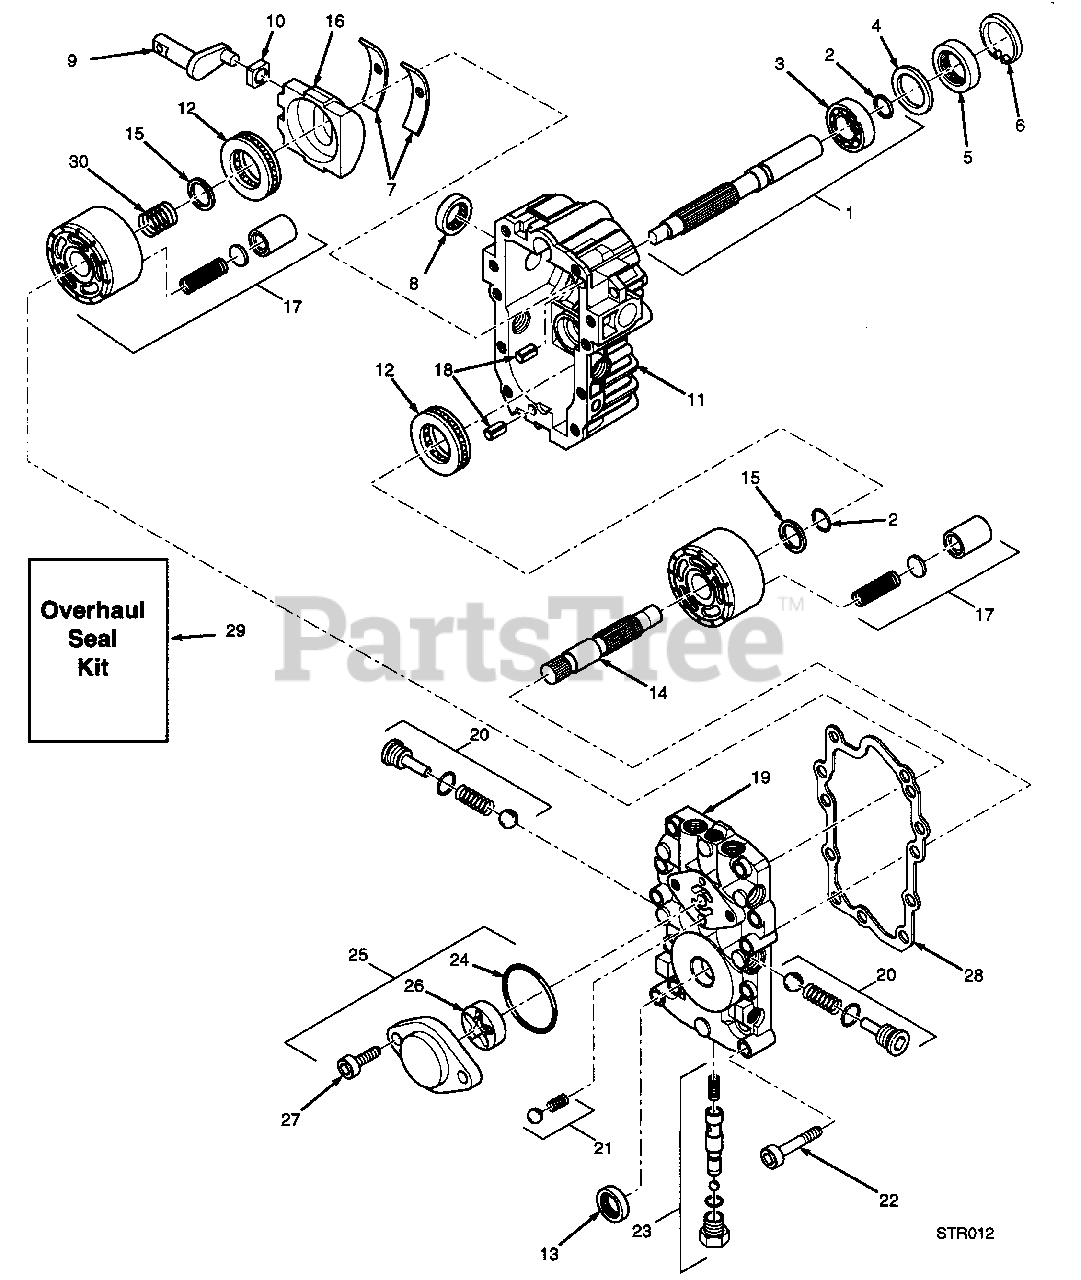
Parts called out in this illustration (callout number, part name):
1	PUMP SHAFT KIT
2	WIRE RETAINING RING
3	BALL BEARING
4	SPACER
6	RETAINING RING
7	CRADLE BEARING
9	TRUNNION ARM
10	SLOT GUIDE
11	TRANSMISSION HOUSING KIT(L.H.)
11	TRANSMISSION HOUSING KIT(R.H.)
12	THRUST BALL BEARING ASSEMBLY
14	MOTOR SHAFT
15	BLOCK THRUST WASHER
16	VARIABLE SWASH PLATE
17	BDT-10L BLOCK ASSEMBLY
18	PIN ST HOLDER
19	CENTER SECTION KIT
20	CHECK VALVE KIT
21	CHARGE RELIEF KIT
22	SOCKET HEAD CAPSCREW
23	BYPASS VALVE KIT
24	O-RING
25	CHARGE PUMP COVER
26	GEROTOR ASSEMBLY
28	CENTER SECTION GASKET
29	OVERHAUL SEAL KIT
30	SPRING BLOCK
